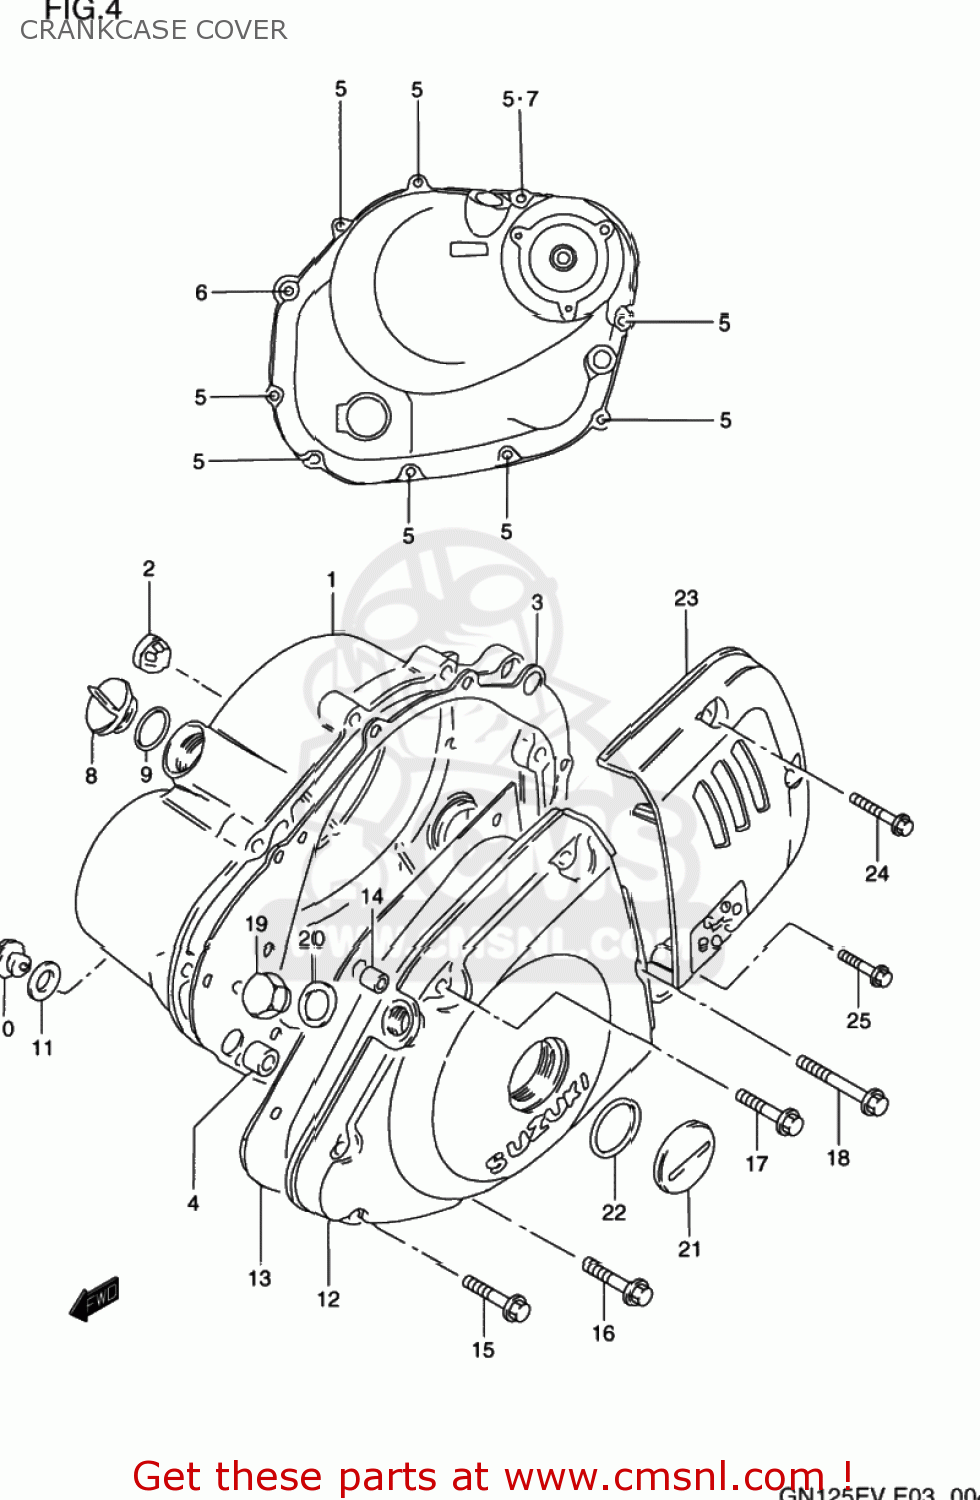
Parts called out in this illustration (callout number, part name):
1	COVER,CLUTCH
2	LENS,OIL LEVEL CHECK
3	GASKET,CLUTCH COVER (NAS)
4	PIN
5	BOLT
6	BOLT
7	GASKET(5.8X11X1.2) (NAS)
8	PLUG(20X10)
9	O RING(D:3.1,ID:16.8)
10	PLUG(14X12)
11	GASKET(13.8X18.8X4.8) (NAS)
12	COVER,MAGNETO
13	GASKET,MAGNETO COVER (NAS)
14	PIN
15	BOLT
16	BOLT
17	BOLT
18	BOLT
19	PLUG,12X9
20	GASKET(12.1X16.2X3.7) (NAS)
21	PLUG(26X9)
22	O RING(D:3.1,ID:22.7)
23	COVER,ENGINE SPROCKET
24	BOLT
25	BOLT
